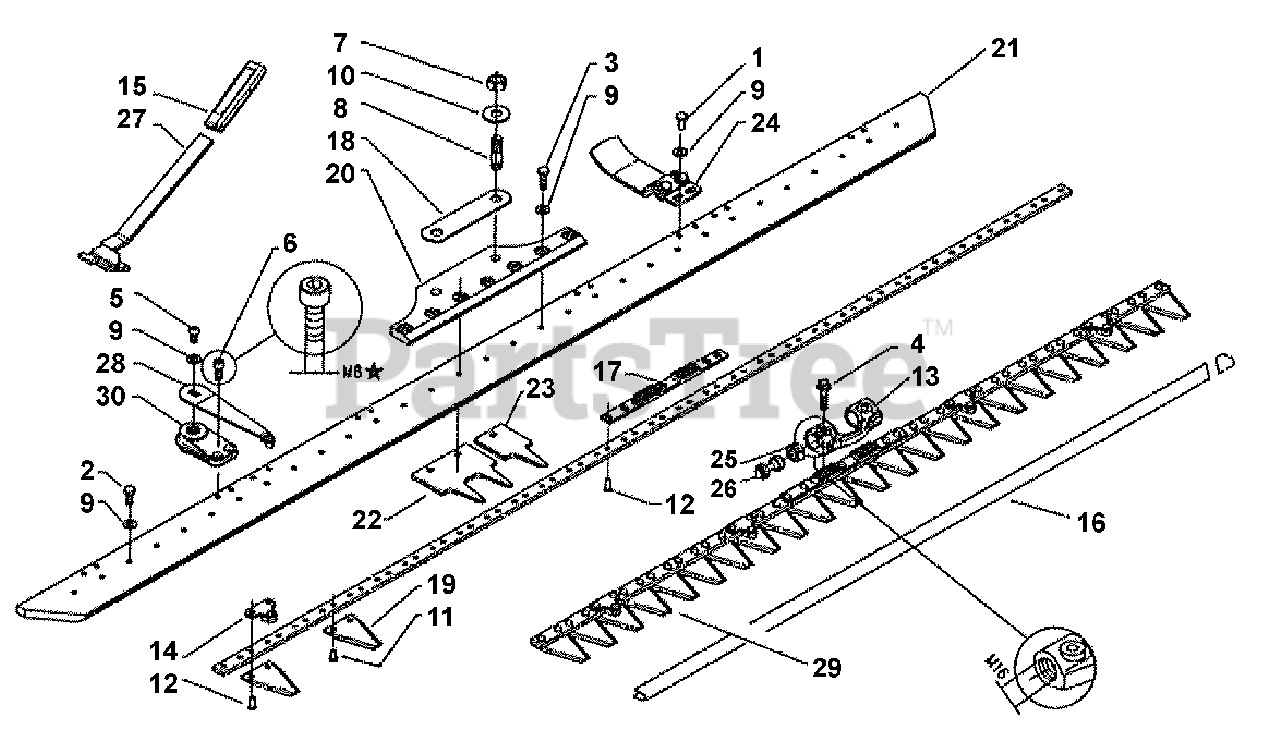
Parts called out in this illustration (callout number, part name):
1	SCREW, M8X16
2	SCREW, M8X20
3	SCREW, M8X25
5	SCREW, M8X16 7380-8G
7	NUT, M14X1.5
8	STUD, M14X1.5X48X12X20
10	WASHER, M14 SUPER
11	RIVET, M6.5X13
12	RIVET, M6.5X16
17	SMALL PLATE
19	BLADE SECTION
21A	CONVEYING CHUTE 45"
21B	CONVEYING CHUTE 53"
22	DOUBLE TOOTH
23	SIMPLE TOOTH
25	CONICAL NUT
26	SCREW FOR BLADE CONNECTION
27	SPRING LIFTER
